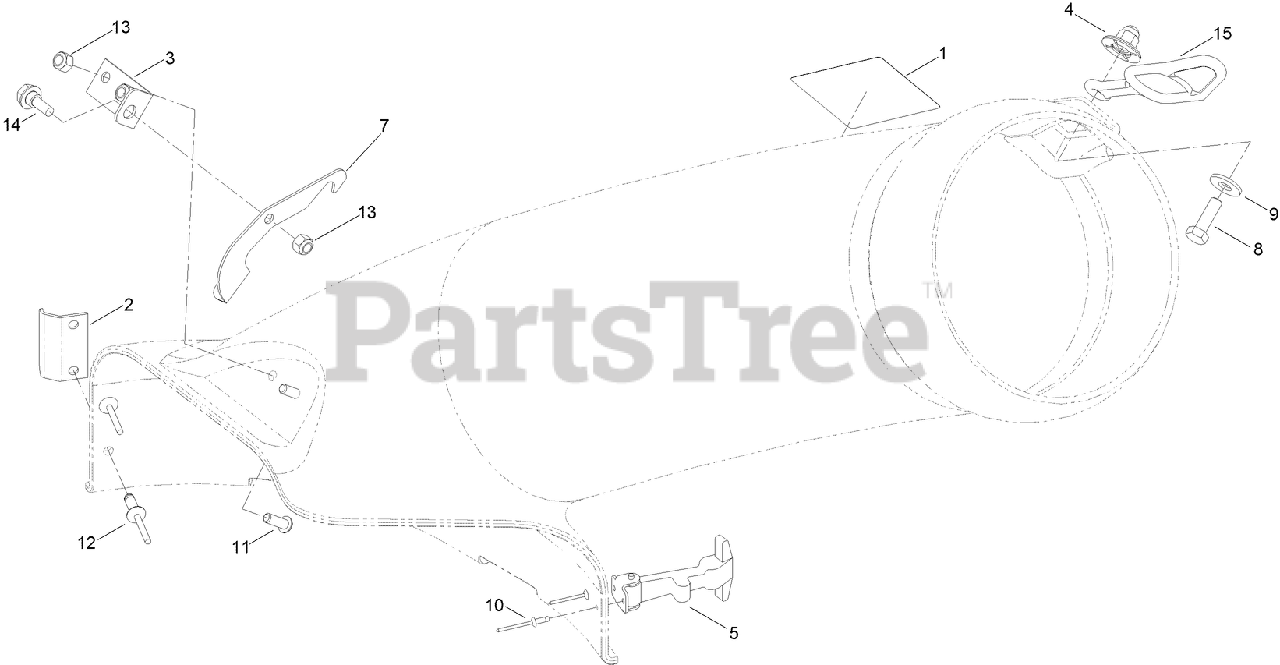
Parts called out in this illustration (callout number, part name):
1	DECAL-DANGER
2	BRACKET-ELBOW
3	PLATE-PIVOT
4	NUT-IMPELLER
5	HANDLE ASM
8	SCREW-HH
9	WASHER-FLAT
10	RIVET-POP
11	SCREW-HSBH
12	RIVET-BLIND
13	NUT-LOCK, NI
14	SCREW-SHOULDER,HWH
15	RETAINER-DUCT
